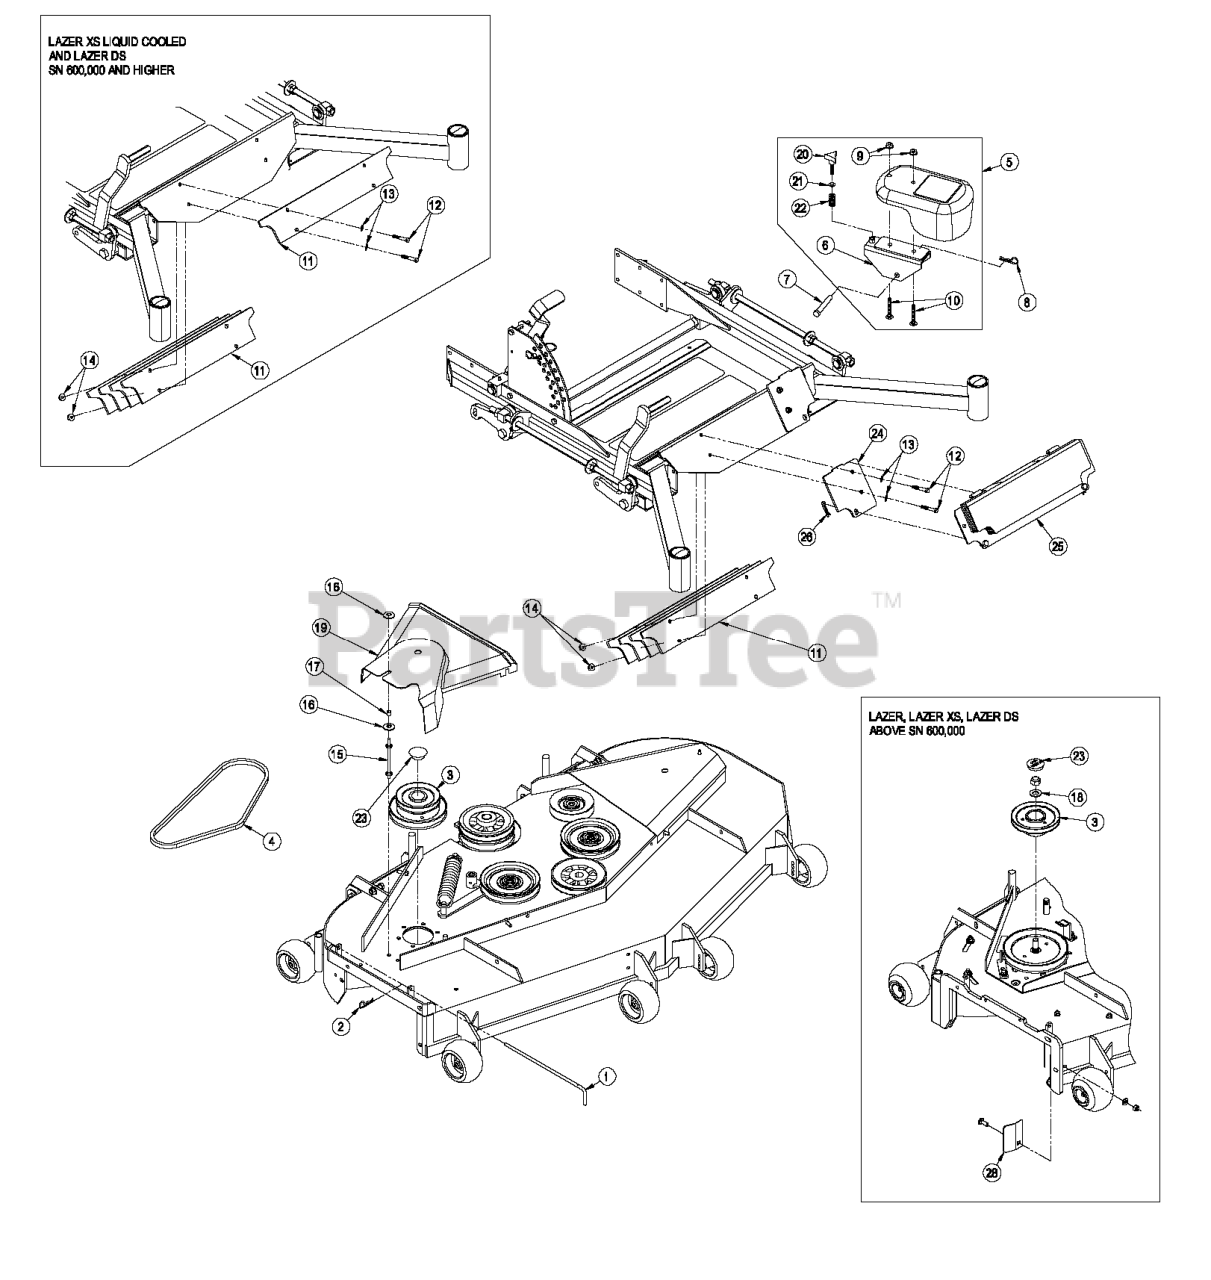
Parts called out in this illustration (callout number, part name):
1	Pin, Chute Pivot
2	Hairpin, Cotter
6	Wld, Weight Bracket 2.0
7	Pin, Clevis
8	Hairpin, Cotter
9	Nut, Whizlock 3/8-16
10	Screw, Sq Head 3/8-16 x 2 1/2
11	Plate, Weight
12	Screw, HH 5/16 -18 x 1 3/4
13	Washer, 5/16 SAE
14	Nut, Whizlock 5/16-18
15	Stud, Belt Shield
24	Plate, Weight Mounting
25	Asm, Weight Plate W/Decals
26	Hairpin, Cotter
27	Template, Drill
